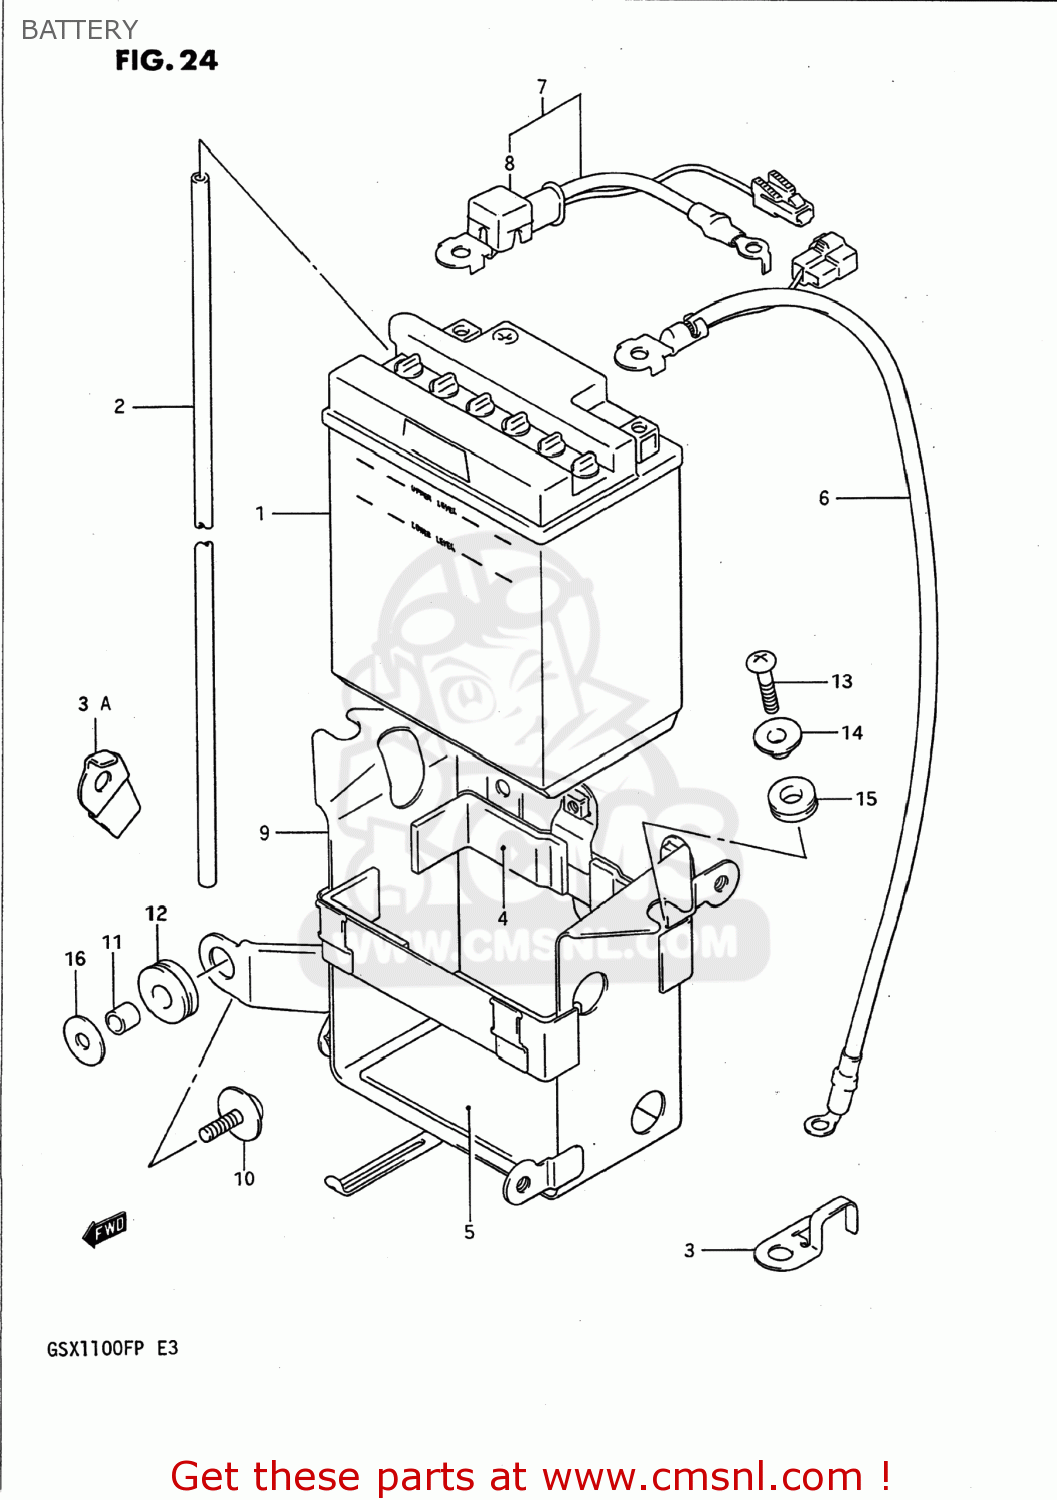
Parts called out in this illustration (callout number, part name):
1	BATTERY ASSEMBLY (12V)
2	HOSE,BATTERY EXHAUST
3	CLAMP,BATTERY EXHAUST HOSE
3A	CLAMP,BATTERY EXHAUST HOSE
4	PROTECTOR,20X9
5	PROTECTOR(170X95X3.0)
6	WIRE,BATTERY MINUS LEAD
7	WIRE,BATTERY PLUS
8	CAP,BATTERY PLUS
9	HOLDER,BATTERY
10	SCREW
11	SPACER
12	CUSHION
13	SCREW, CENTER
14	WASHER
15	CUSHION
16	WASHER(6,5X22X1.6)
